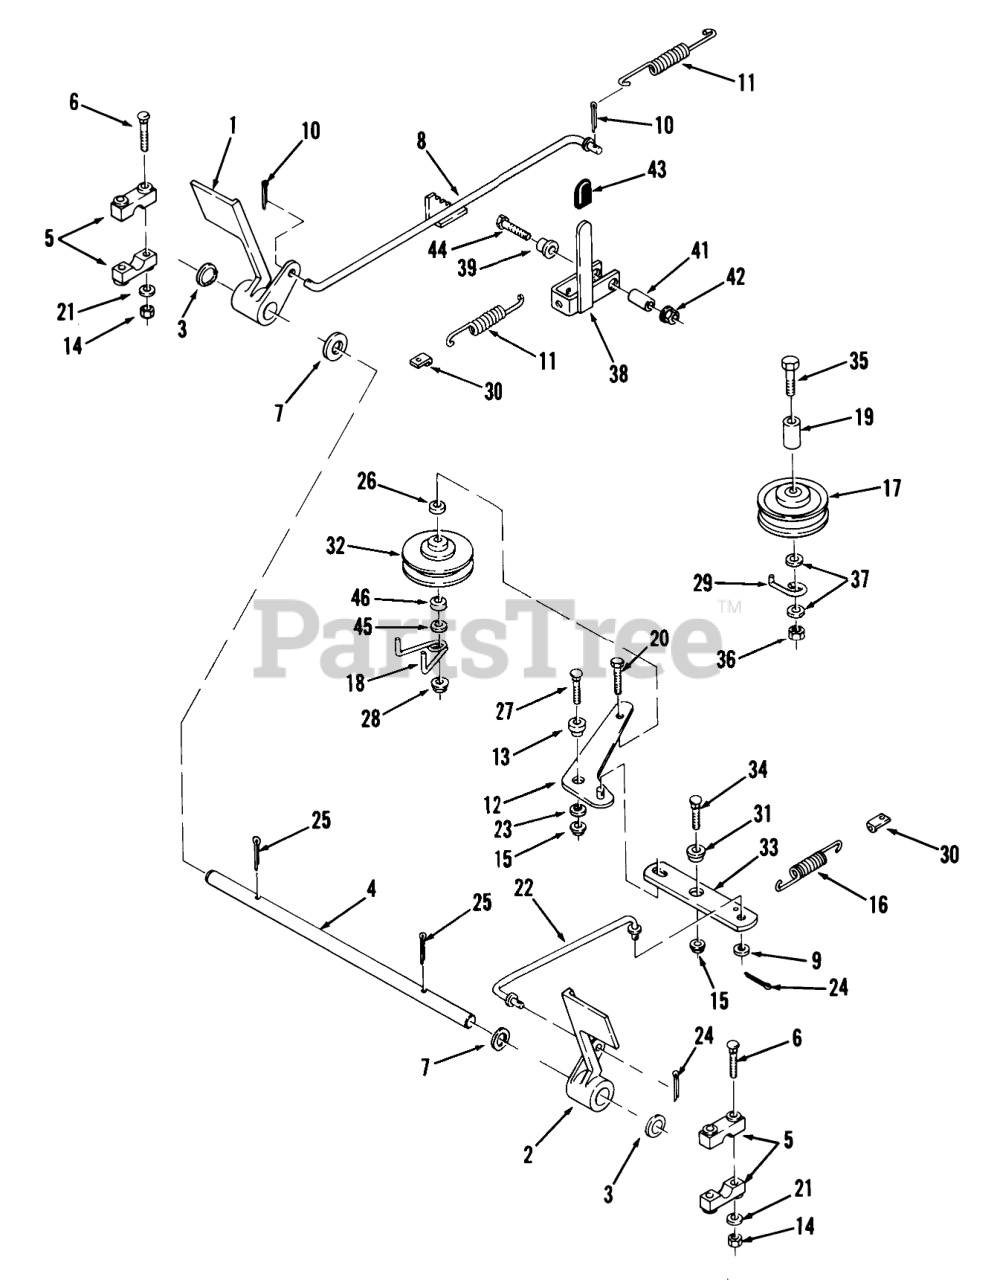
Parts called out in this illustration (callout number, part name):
1	PEDAL-BRAKE R
2	Pedal Clutch
3	Special Washer
4	Shaft-Pedal
5	BLOCK PIVOT
6	Washer
7	Washer
8	Assy Brake Rod
9	WASHER 5/16 SAE
10	Pop Rivet
11	SPRING-EXTENSION
12	IDLER ARM ASSY R
13	SPACER-IDLER ARM
14	Nut
15	LOCKNUT-FLANGE
16	SPRING
17	PULLEY-IDLER STATION
18	RETAINER-BELT
19	SPACER
20	Bolt
21	WASHER 5/16 SAE
22	ROD-CLUTCH R
23	Washer
24	Pop Rivet
26	SPACER
27	Carriage Bolt
28	LOCKNUT-FLANGE
29	RETAINER-BELT
30	CLIP - SPRING
31	SPACER
32	IDLER PULLEY
33	BAR-CLUTCH
34	Bolt
35	Bolt 3/8-16 x 3 1/4
36	Nut
37	Washer
38	PAWL-HANDLE ASSY
39	SPACER
41	SPACER
42	LOCKNUT-FLANGE
43	GRIP
44	Bolt
45	Washer
46	WASHER
